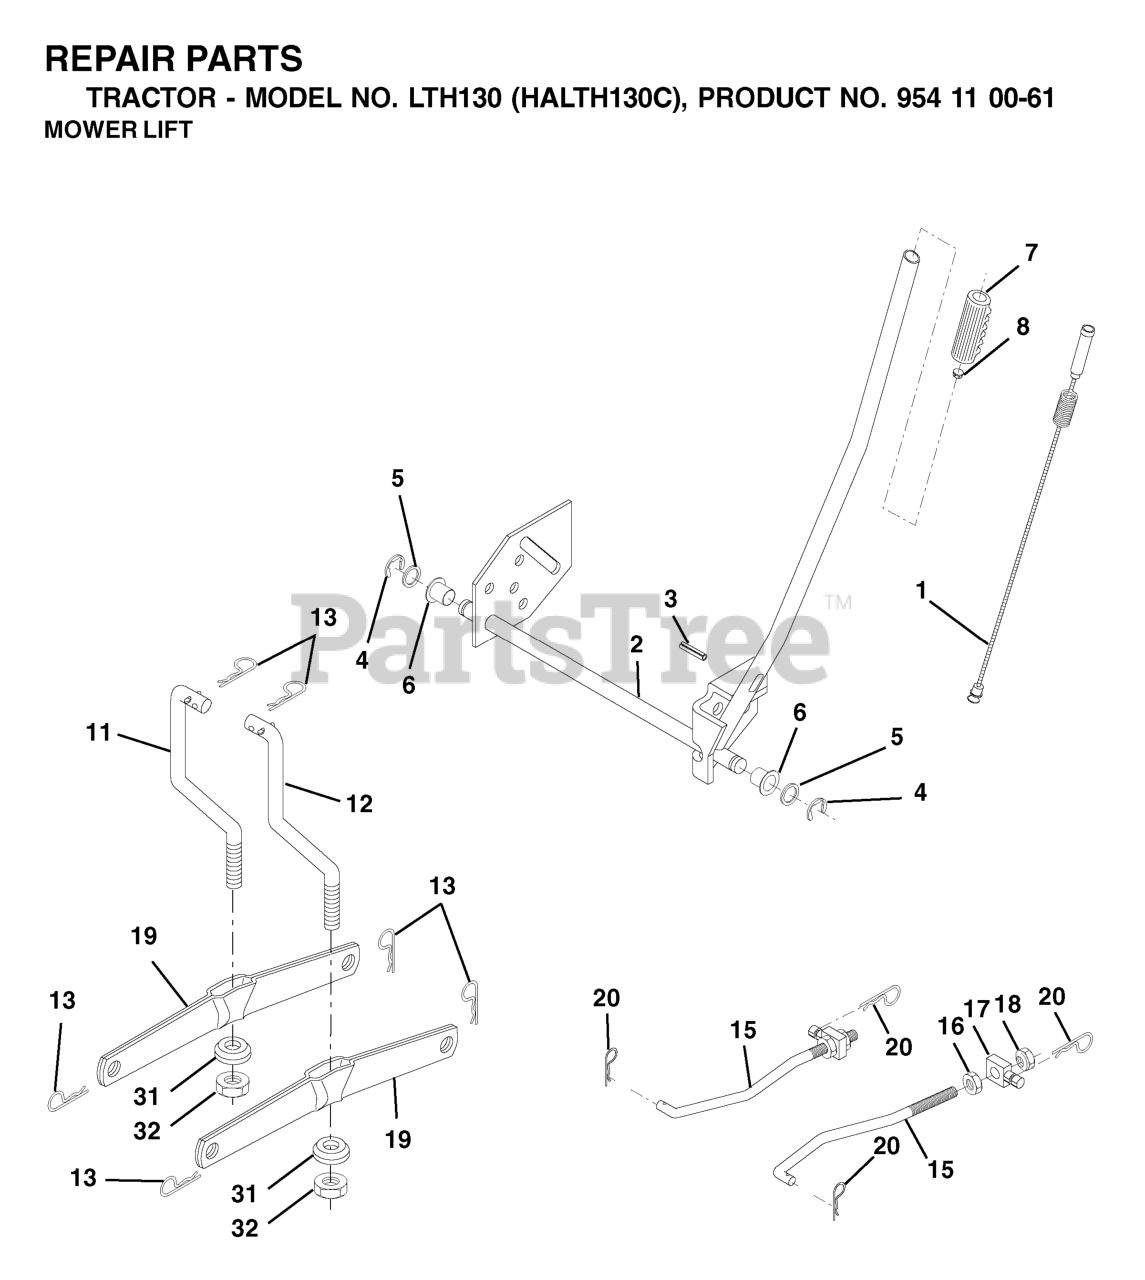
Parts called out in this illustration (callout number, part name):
1	WIRE ASM INNER W/ PLUNGER LT
2	SHAFT ASM R HANDLE
3	PIN GROOVE.
4	RETAINING RING LT
6	BEARING.NYLON
8	PLUNGER BUT KIT
11	LINK LIFT LH
12	LINK LIFT RH
13	RETAINER-SPRNG RB
15	LINK.SUSPENSION.FRONT
16	NUT.HEX.JAM.1/2-13
17	TRUNION
18	NUT.LK.W/WSH.1/2.
19	ARM.REAR.SUSPENSION
20	SPRING RETAINER
31	BEARING.PIVOT.LIFT
32	NUT CROWNLOCK 3/8-24
